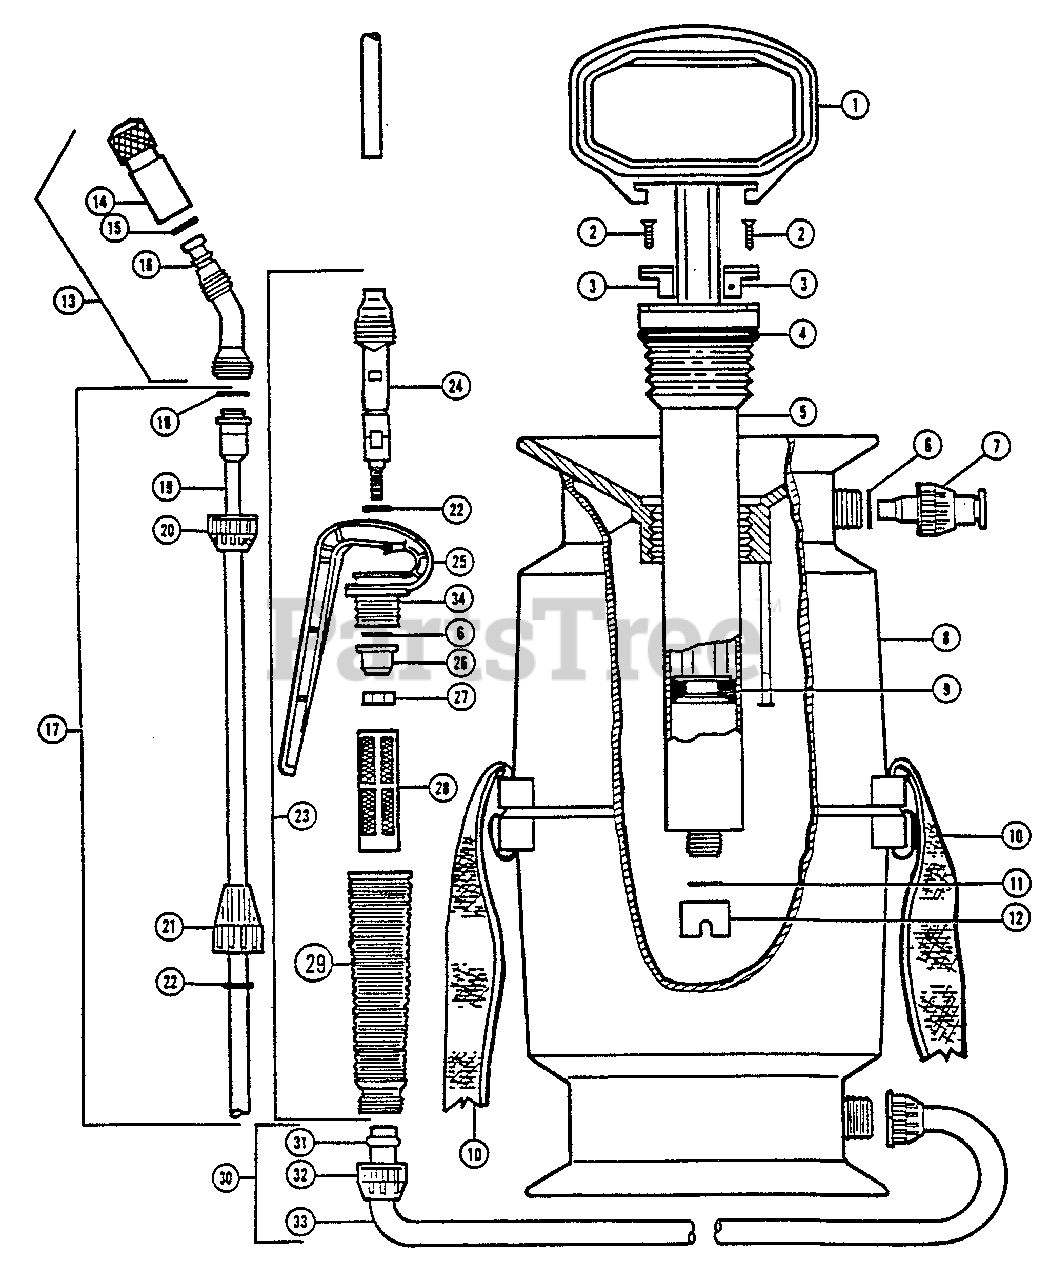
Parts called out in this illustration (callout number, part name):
2	SCREW - 7×7/8 -- FLAT HEAD
3	CHAMBER COVER
4	O-RING AN 30
5	CHAMBER MS-9, 12
6	O-RING AN 8
6A	O-RING - 8
7	PRESSURE RELEASE VALVE
8	TANK -- MS-9
8A	TANK
9	COLLAR SEAL
9A	COLLAR SEAL, VITON
10	STRAP
11	CLOSING VALVE
12	VALVE NUT
12	WAND ASSY
13	NOZZLE ASSY
14	NOZZLE - 1 MM
15	O-RING AN 5
15A	O-RING - 5
16	SPRAYER
17	TUBE ASSY
18	WASHER
19	WAND TUBE
21	WAND NUT
22	O-RING AN-6
22A	O-RING - 6
23	HANDLE ASSY
24	WAND SHAFT
25	BODY, HANDLE
28	FILTER, WAND
30	HOSE ASSY
31	HOSE CAP
33	HOSE - 6×1.3M
34	O-RING
